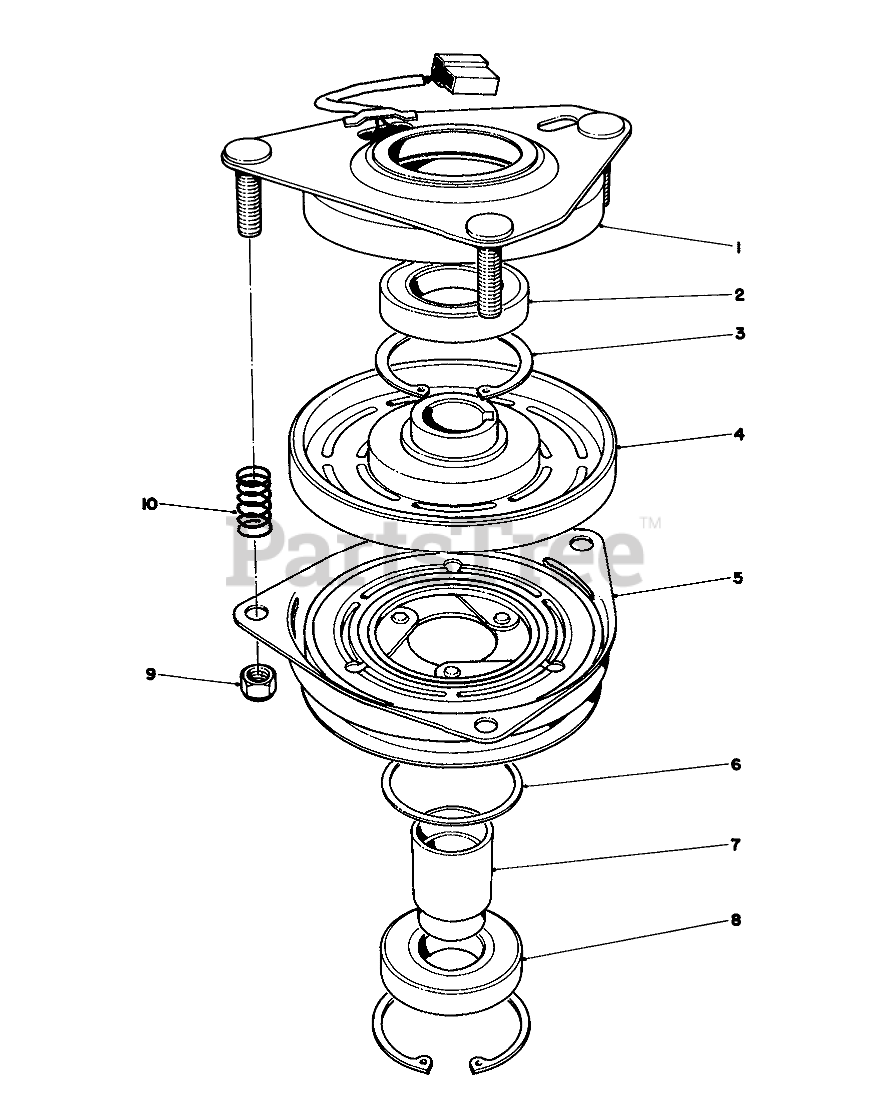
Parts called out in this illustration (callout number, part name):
1	Field Assembly (Incl. Ref. #2 & 3)
2	BEARING-FIELD
3	RING-RETAINING
4	Field Coil, Rotor & Bearing Assembly (Incl. Ref. #1)
5	Armature & Pulley Assembly (Incl. Ref. #3, 6, 7 & 8)
6	SPACER-BEARING, PULLEY
7	COLLAR-BEARING
8	BEARING-PULLEY
9	NUT-LOCK
10	SPRING
